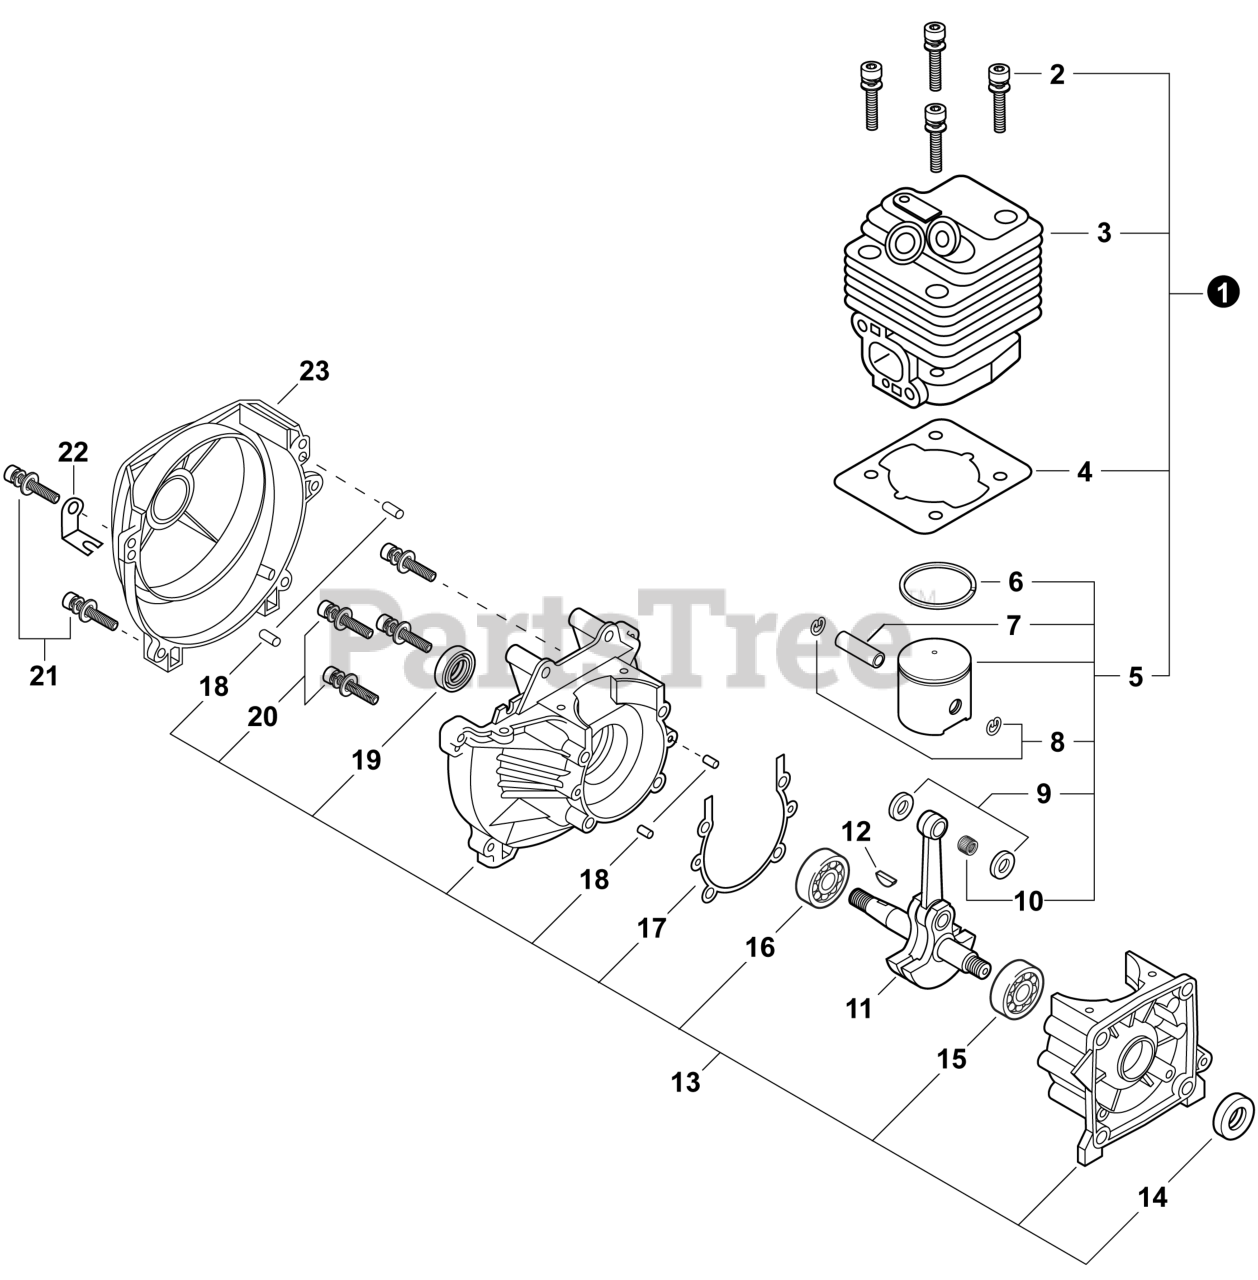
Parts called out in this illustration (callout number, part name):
1	REPAIR KIT, ENGINE
2	BOLT 5x20
3	CYLINDER
4	GASKET, CYLINDER
5	PISTON KIT
6	RING, PISTON
7	PIN, PISTON 10
8	RING, SNAP 10
10	BEARING, NEEDLE 10
11	CRANKSHAFT ASSY
12	KEY, WOODRUFF 3x14
13	CRANKCASE KIT
14	SEAL, OIL 12
15	BEARING, BALL 6202
16	BEARING, BALL 6201
17	GASKET, CRANKCASE
18	PIN, LOCATING 4x8
19	SEAL, OIL
20	BOLT M5x35
21	BOLT 5x20
22	HOLDER, CABLE
23	COVER, FAN
